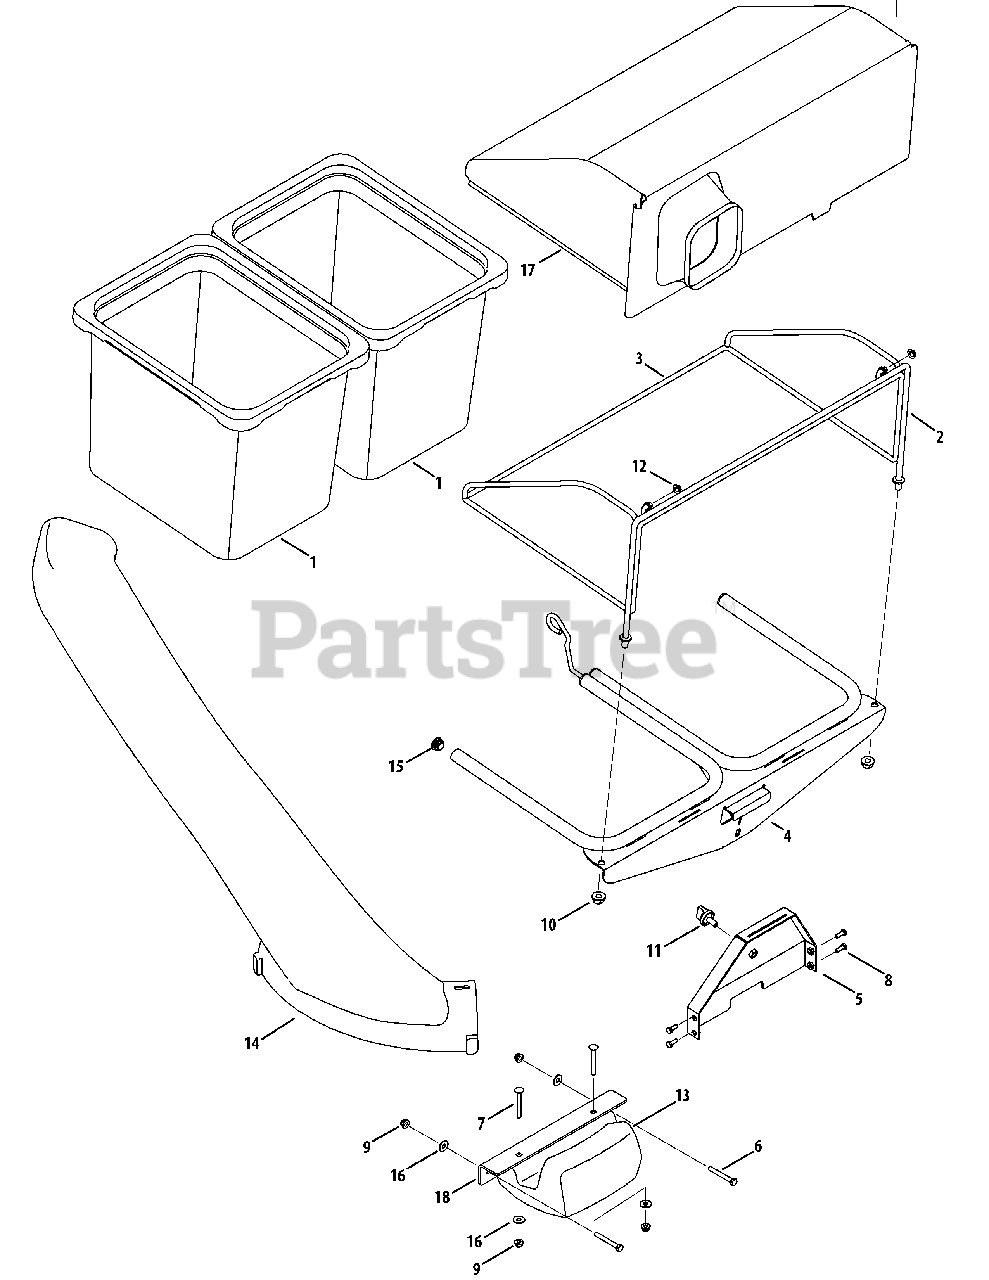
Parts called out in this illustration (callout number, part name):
2	Front Hood Assembly Frame
3	Rear Hood Assembly Frame
4	Bagger Support Assembly
5	Mounting Bracket
6	Hex Lock Screw, 5/16-18, 2.50
7	Carriage Bolt, 5/16-18, 2.50
8	Hex Head Screw, 5/16-18, .750
9	Flange Lock Nut, 5/16-18
10	Flange Lock Nut, 1/2-13
11	Knob, 3/8-16, .875
12	Push Cap, 3/8 Rod
14	Chute Tube
16	Flat Washer, .349 x .879 x .063
17	Grass Catcher Hood
18	Weight Mounting Bracket
